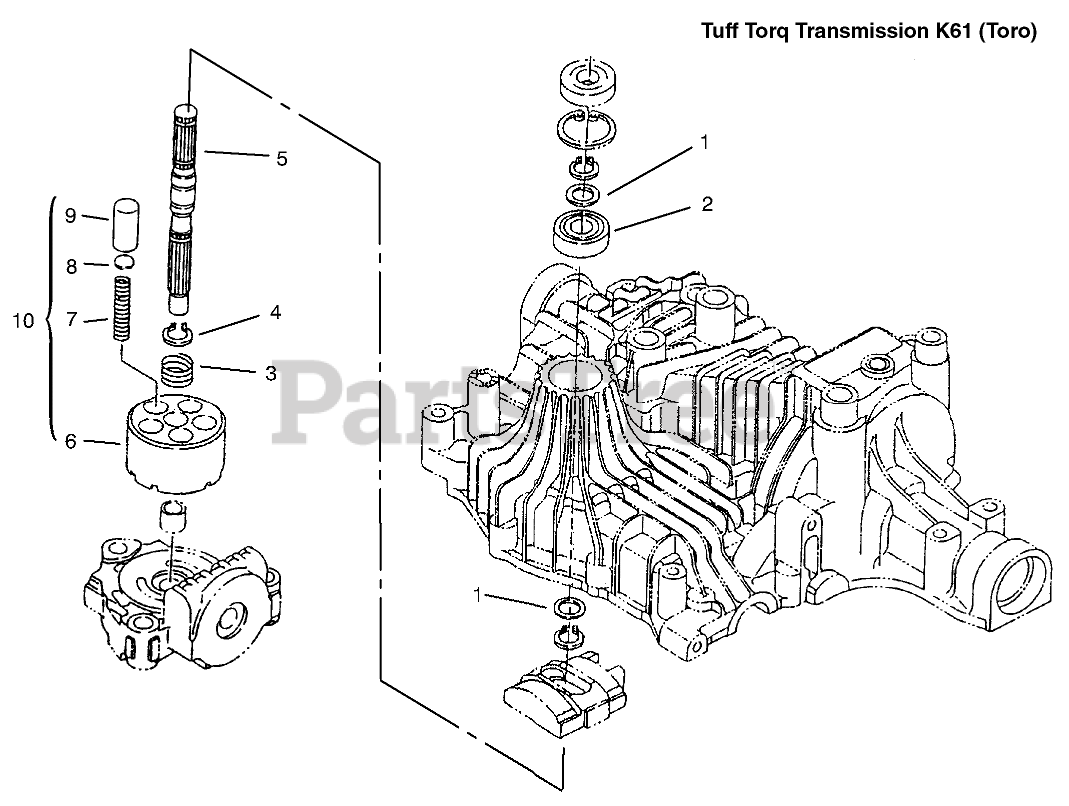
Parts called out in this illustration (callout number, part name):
1	WASHER
2	BEARING-BALL
3	SPRING
4	RING-SNAP
5	SHAFT - PUMP
6	Block-Cylinder
8	Washer
10	ASM - CYCLINDER INC 6-9
